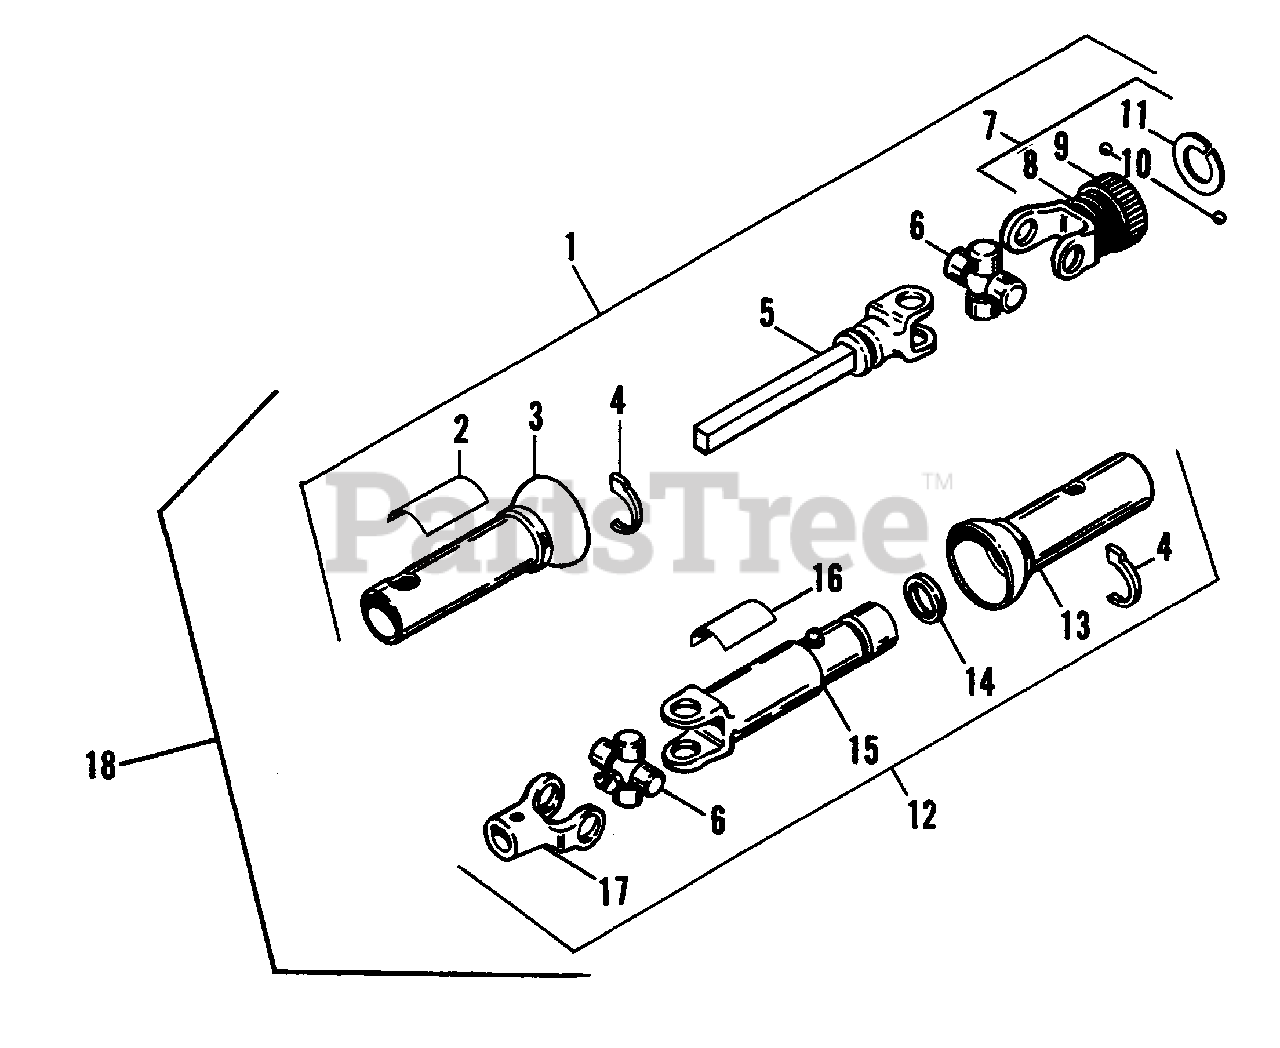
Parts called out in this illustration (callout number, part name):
1	DRIVE SHAFT ASSY., Tractor Half
2	SHIELD DECAL
3	SHIELD, Outer
5	YOKE & SHAFT ASSY.
6	JOURNAL ASSY.
7	YOKE ASSY.
12	DRIVE SHAFT ASSY.-Implement Half
13	SHIELD, Inner
14	NYLON BEARING
15	YOKE & TUBE ASSY.
16	DANGER LABEL
18	COMPLETE Drive ASSY
